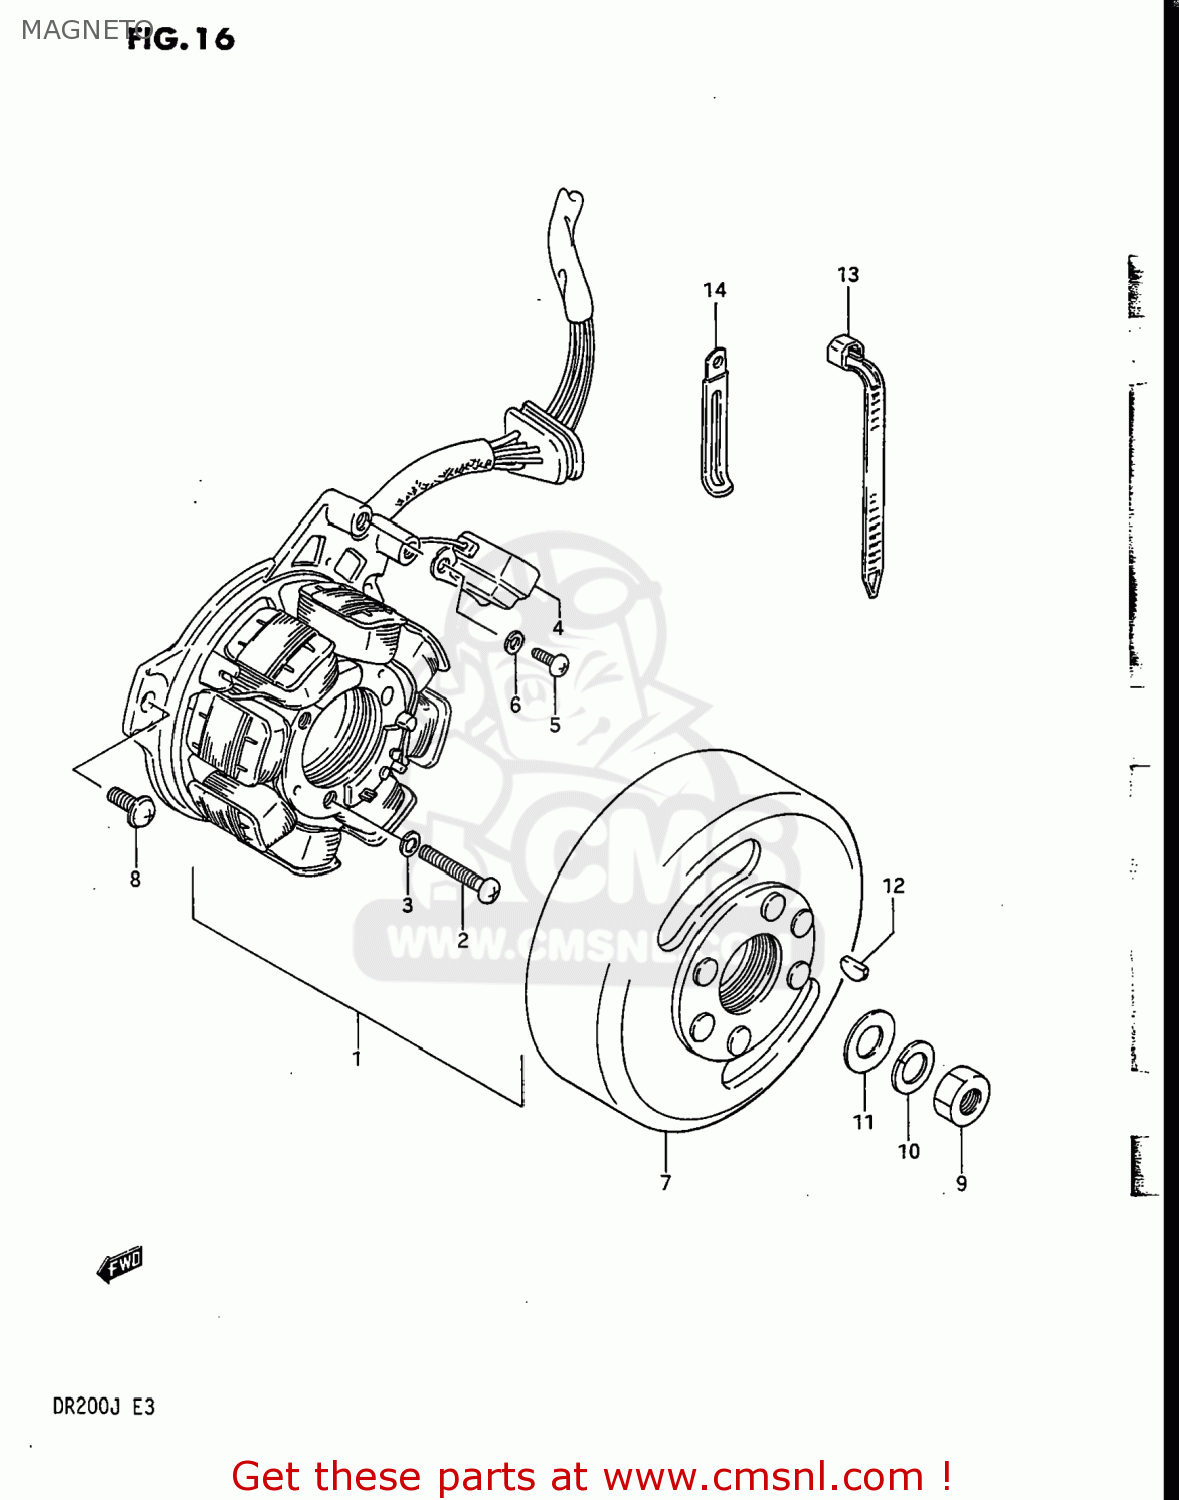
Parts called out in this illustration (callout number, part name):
1	STATOR ASSEMBLY
2	SCREW
3	LOCK WASHER
4	COIL,PICK UP
5	SCREW
6	WASHER,LOCK 4M
7	ROTOR ASSEMBLY
8	SCREW(5X14)
9	NUT (10MM)
10	WASHER,LOCK,10
11	WASHER
12	KEY
13	CLAMP(L:125)
14	CLAMP
